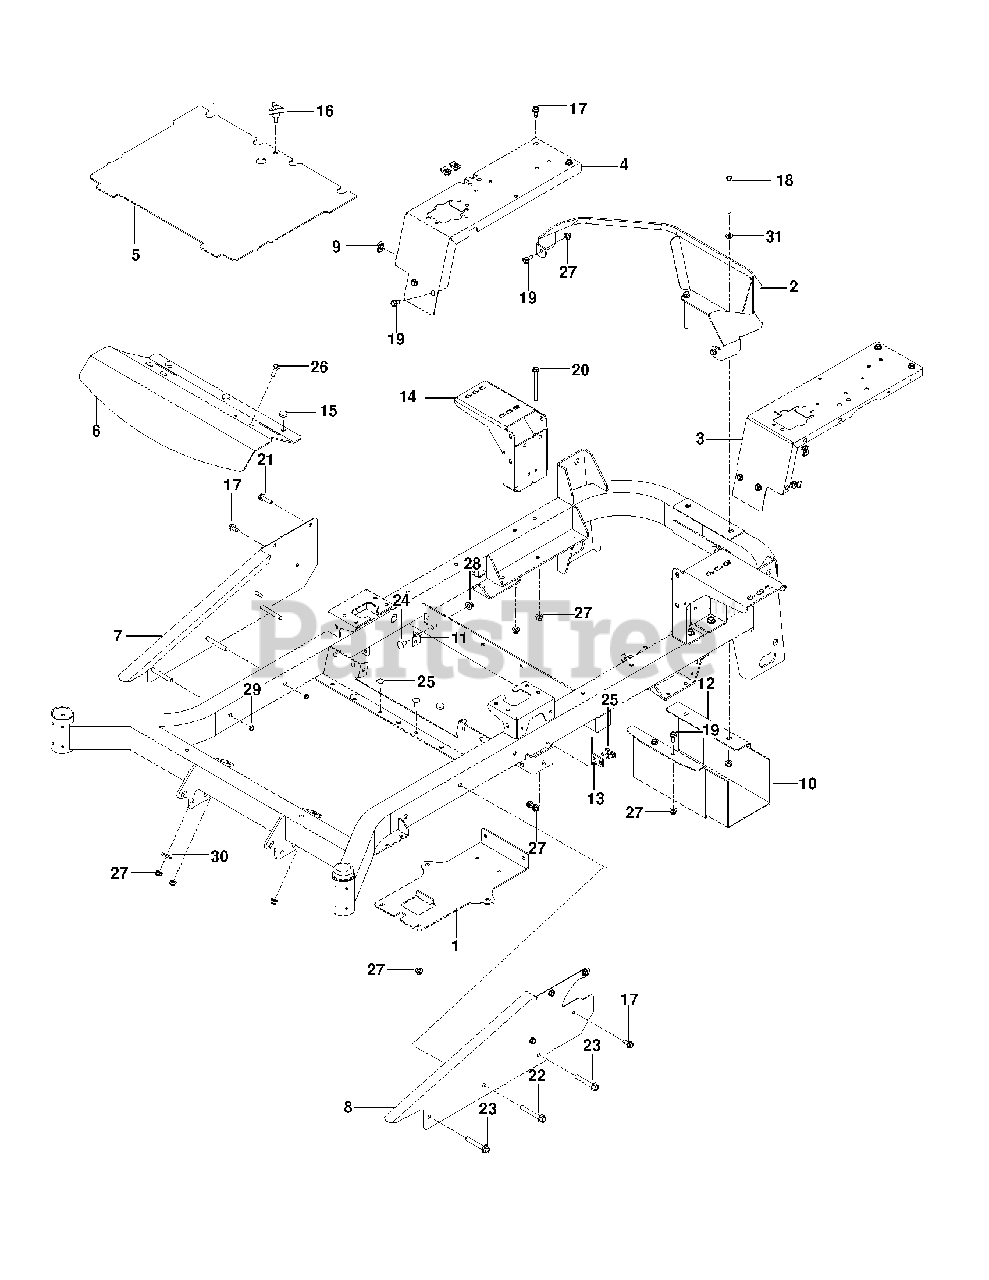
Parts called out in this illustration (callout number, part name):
1	PLATE, BATTERY, BLACK
2	GUARD, REAR MZ, GRAY
3	PANEL.FILLER.LT.ORANGE
4	PANEL.FILLER.RT.ORANGE
5	PLATE, FLOOR W/DECALS
6	PLATE, FOOTREST
7	SIDE.RT.ORANGE
8	SIDE.LT.ORANGE
9	U-CLIP 5/16-18 NUT RETAINER
10	HEAT SHIELD
11	BRACKET.DAMPENER.BLACK
12	SHIELD.MUFFLER.BLACK
13	STOP, DECK, EZ+
14	MOUNT, TANK, ZT BLK
15	GROMMET, BUMPER
16	KNOB W/STUD
17	BOLT 5/16-18 X 3/4
18	HCS 5/16C X 4
19	HHFS 5/16-18 X 3/4
20	HHFS 5/16-18 X 3 3/4
21	HHFS 5/16-18 X 1.25 TPBLT GD 5
22	HHFS 3/8-16 X 2 3/4
23	HHFS 3/8-16 X 2.5 GR 5 ZD
24	RHSNB 3/8-16 X 3/4 GR 5 BLK ZN
25	BOLT 5/16C X 3/4" CARRIAGE
26	RHSNB 5/16C X 1
27	5/16-18 NYLOC FLANGE NUT
28	NUT 3/8-16 HEX FLG NYLOC ZD
29	NUT HEX 3/8-16 NYLON, THIN
30	WASHER 1/2" FLAT
31	FLAT WASHER 5/16 SAE
